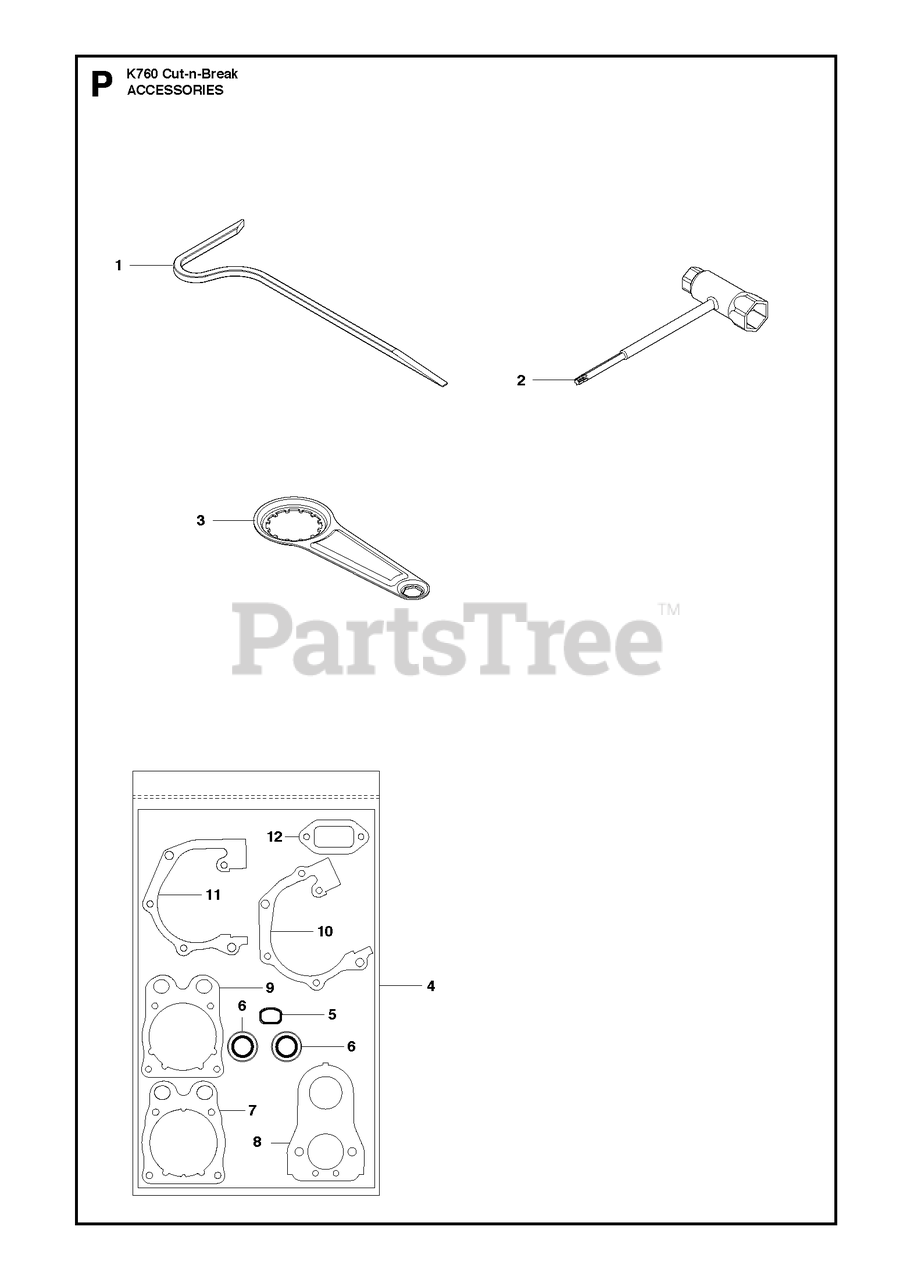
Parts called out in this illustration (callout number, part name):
4	GASKET KIT
6	SEALING RING
8	GASKET
12	GASKET
